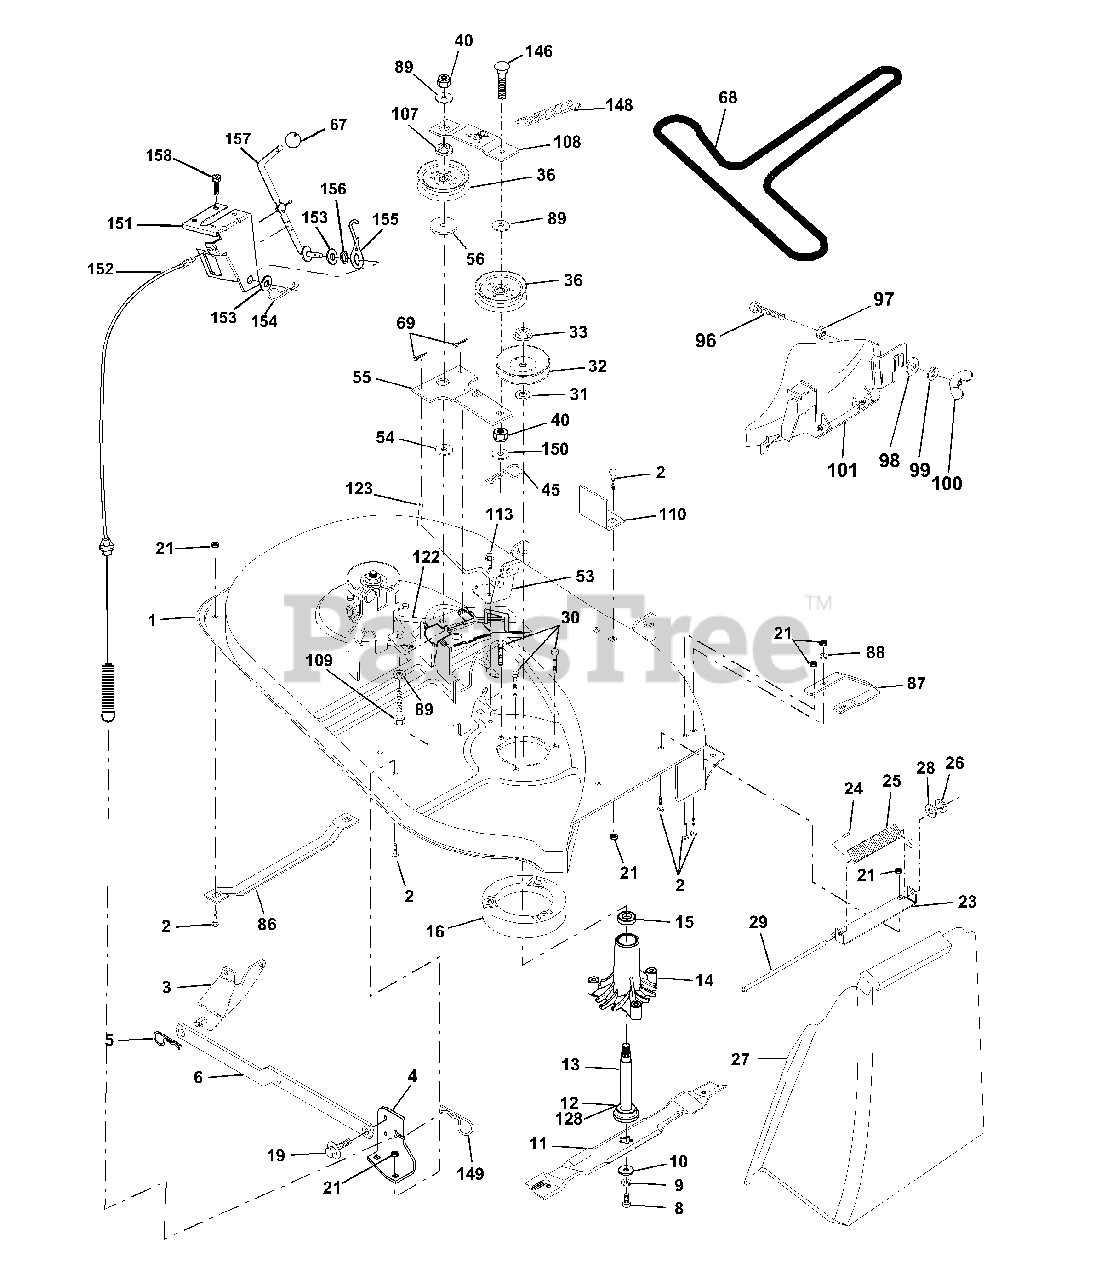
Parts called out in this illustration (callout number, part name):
1	Mower Housing Assembly
2	Bolt Carriage 5/16-18 x 3/4
3	Bracket Asm Fr. Sway Bar
4	Bracket Deck Sway Bar 38"/42"
5	Retainer Spring
6	Arm, Suspension, Rear
8	Bolt 3/8-24 x 1.25 Grade 8
9	Washer, Lock 3/8
10	Washer,Hardened
11	Blade Mower
12	Bearing, Ball
13	Shaft Assembly, Mandrel, Vented
14	Housing, Mandrel, Vented
15	Bearing, Ball, Mandrel
16	Stripper, Vented Mower Deck
19	Bolt, Shoulder
21	Nut
23	Bracket, Mower Deflector
24	Cap, Sleeve
25	Spring, Torsion, Deflector
26	Nut, Push
27	Shield, Deflector
28	Washer 11/32 x 5/8 x 16 Gauge
29	Rod, Hinge
30	Screw Thdrol. Washer Head
31	Washer, Spacer
32	Pulley, Mandrel
33	Nut, Toplock 9/16
36	Pulley, Idler, Flat
40	Nut, Crownlock 3/8-16 Unc
45	Retainer
53	Brake Assembly
54	Washer,Hardened
55	Idler Arm Assembly
56	Spacer, Retainer
67	Knob
68	V-Belt, 42" Mower
69	Pin, Cotter 3/32 x 3/4
86	Runner,LH
87	Runner,RH
88	Washer 11/32 x 3/4 x 16 Ga
89	Washer 13/32 x 1 x 12 Ga.
96	Bolt 3/8-16 x 1-1/4 Mulcher
97	Nut Centerlock 3/8-16 Unc
98	Washer 13/32 x 1-1/4 x 16 Ga.
99	Washer Lock Hvy Hlcl Spr 3/8
100	Nut Wing
101	Cover Asm Mulching 38"
107	Spacer Retainer
108	Stiffener, Idler Arm
109	Bolt, Hex Hd 3/8-16 x 2-1/2
110	Upstop Deck Front 38"
113	Screw 5/16-1/ x 3/4
122	Rod, Brake LH
123	Rod, Brake RH
128	Washer Felt
146	Bolt Carriage Idler
148	Spring Return Idler
149	Retainer Spring Yellow
150	Washer 9/32 x 3/4 x 16 Ga.
151	Bracket Clutch Cable
152	Clutch Cable 38"/46"
153	Washer Flat 3/8" Type B
154	Spring Retainer
155	Spring Retention LVR CLTCH CAB
156	Spacer Clutch Cable
157	Rod Clutch Cable 3/8"
158	Screw Hex Thd Cut 1/4-20 x 5/8
